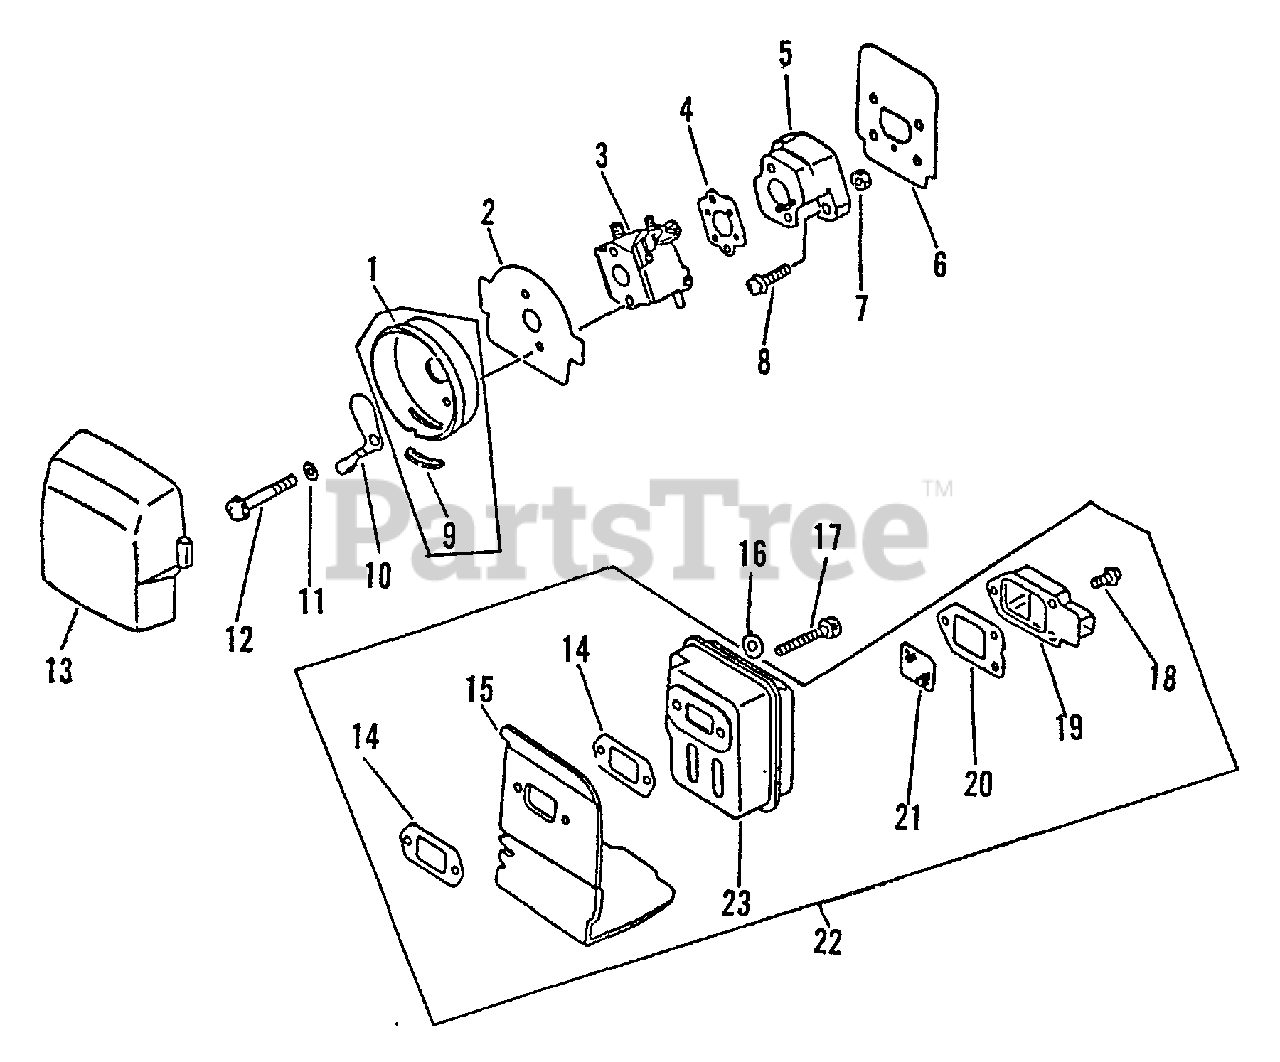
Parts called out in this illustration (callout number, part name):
1	CASE, AIR FILTER
2	PLATE, AIR FILTER
3	CARBURETOR - C1U-K9
4	GASKET, INTAKE
5	INSULATOR, INTAKE
6	GASKET, INTAKE
7	NUT M5
8	SCREW 5×20
9	BUSHING
10	SHUTTER, CHOKE
11	WASHER 5.2×8×0.8T
12	SCREW 5×57
13	FILTER, AIR
14	GASKET, EXHAUST
15	COVER, EXHAUST
16	WASHER, FLAT 5.5×10×0.8
17	BOLT 5×55
18	SCREW 4×10
19	GUIDE, EXHAUST - INNER
20	GASKET, EXHAUST
21	SCREEN, SPARK ARRESTER
22	MUFFLER ASSY
